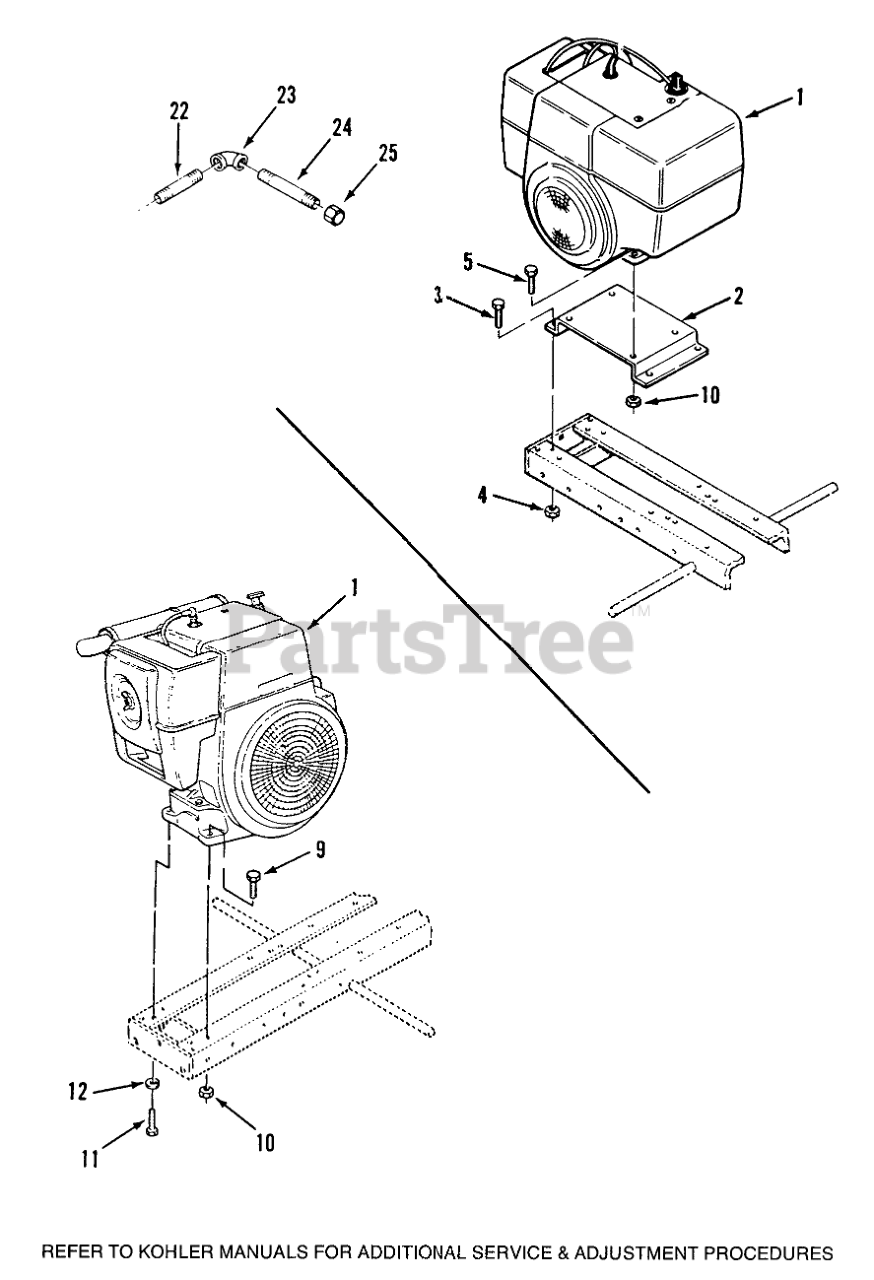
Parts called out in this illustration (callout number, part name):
1	Engine 16HP-Onan P-216-316-8 Only
2	Engine Plate
3	BOLT
4	Nut
5	Bolt
9	BOLT
10	NUT
11	BOLT
12	LOCKWASHER
22	Pipe
23	ELBOW 3/8 90 DEG
24	PIPE-NIPPLE 3/8 X 4"
25	Cap
